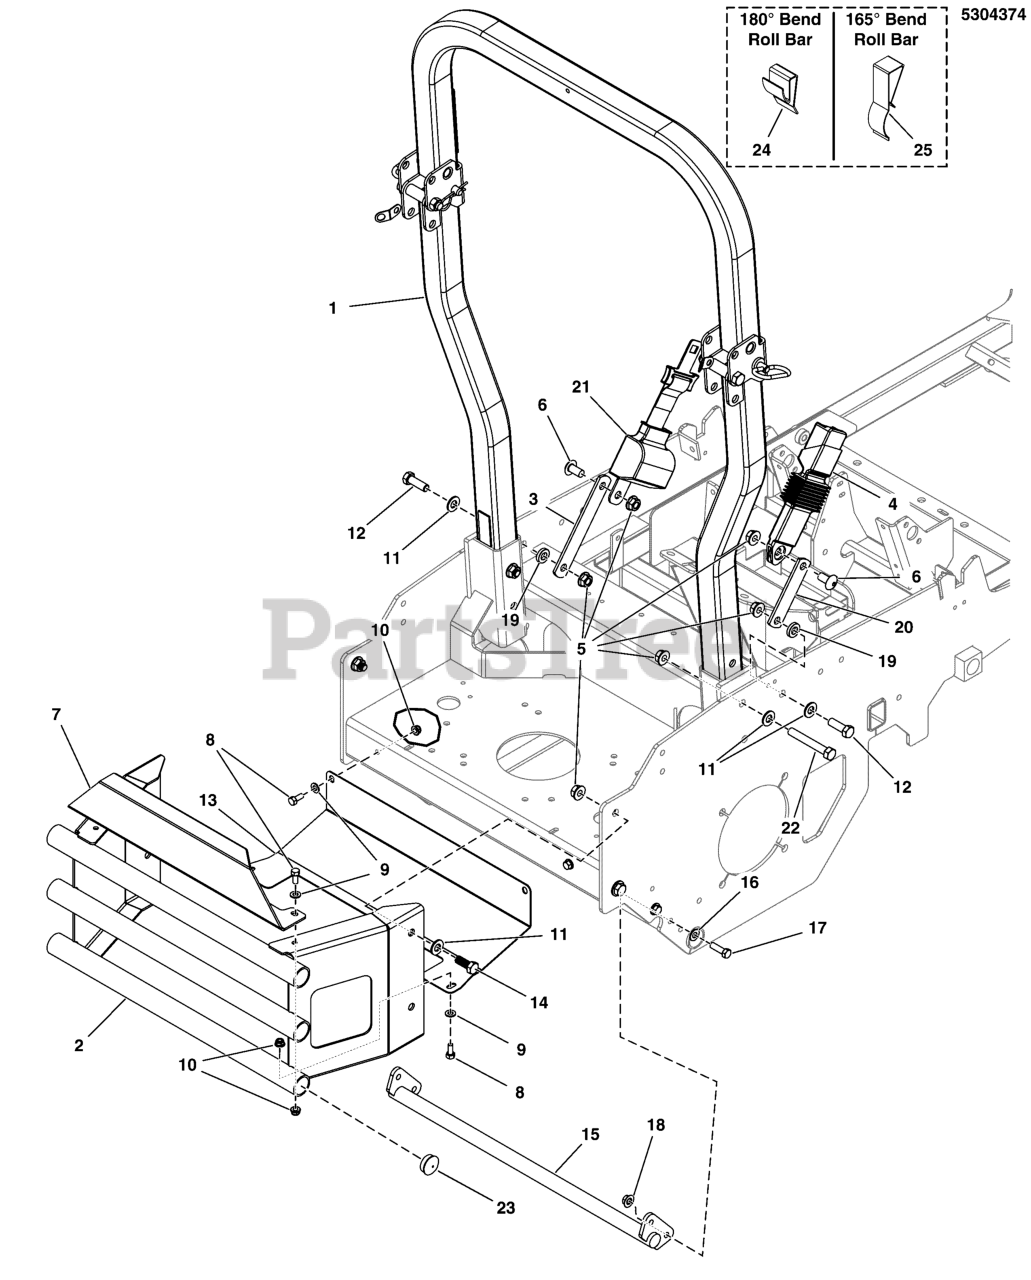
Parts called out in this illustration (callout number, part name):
1	ROLL BAR
2	WELD, BUMPER, F160Z - RED
3	BAR, MOUNT, SEAT BELT, IS700Z - BLK
4	SEAT BELT ASSM, RETRACTOR + SUP SLEEVE
5	NUT, Hex Flange, Nylock, 1/2-13
6	SCREW, 1/2-13 X 1.00, SHCS
7	PLATE, CARB PROTECTOR, F160Z - RED
8	BOLT, 5/16-18 X 3/4 GD5
9	WASHER, 5/16" SAE
10	NUT, 5/16-18 HEX NYLOCK FLANGE
11	WASHER, 1/2 SAE
12	BOLT, 1/2-13 X 1-1/2 GD5 CZ
13	PLATE, HEAT SHIELD, F160Z - BLK
14	BOLT, 1/2-13 X 1-1/4 GD5 CZ
15	WELD, BUMPER, REAR BRAKE - RED
16	WASHER, 3/8 SAE
17	BOLT, 3/8-16 X 1-1/4" GD5 CZ
18	NUT, 3/8-16 HEX SERRATED FLANGE
19	SPACER, .52 X 1.00 X .22, PM, CZ
20	EXTENSION, SEAT BELT - BLK
21	ORDER P/N 5105137 (CONTAINS BOTH SEAT BELT RETRACTOR & SUPER SLEEVE BUCKLE)
22	BOLT, 1/2-13 X 3-1/2, HEX HD, GD5, CZ (SV)
23	PLUG, PANEL, 1.25 - BLACK
24	ANTI-RATTLE SPRING, FEMCO #230328972 (SV)
25	ANTI-RATTLE SPRING, ROPS, 165 DEGREE (SV)
